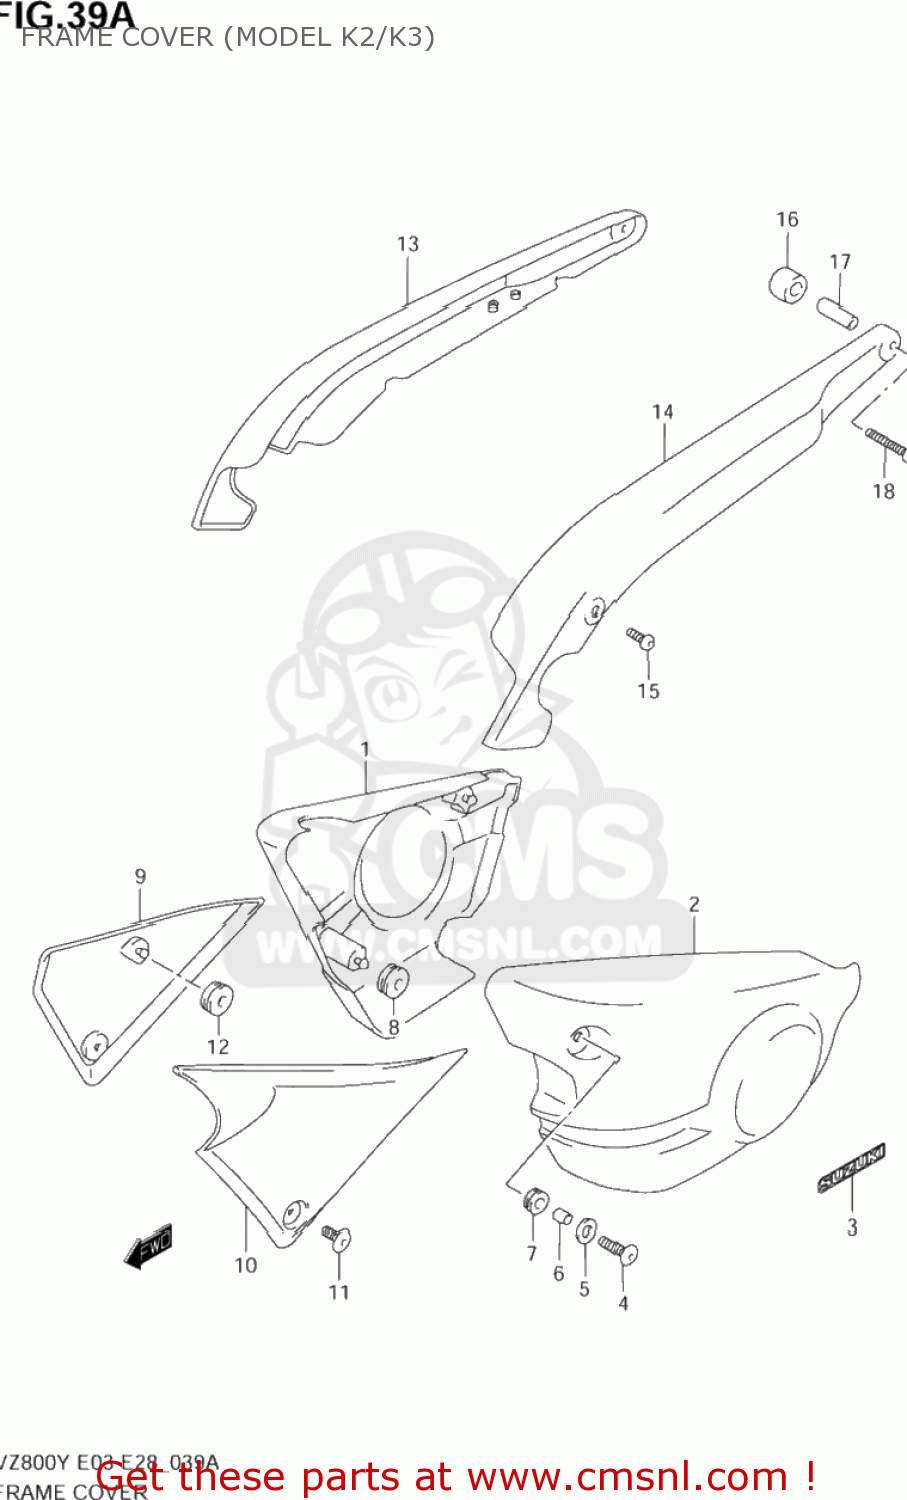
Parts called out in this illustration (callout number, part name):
1	COVER,FRAME,R
2	COVER,FRAME,L
3	EMBLEM,FRAME COVER CTR
4	SCREW(6X16)
5	WASHER(6.5X18X1)
6	SPACER(6.5X9X9)
7	CUSHION
8	CUSHION
9	COVER,FRAME HEAD,R
10	COVER,FRAME HEAD,L
11	SCREW(6X16)
12	CUSHION
13	COVER,FRAME RR,R
14	COVER,FRAME RR,L
15	BOLT(8X16)
16	CUSHION,FRAME RR COVER RR
17	SPACER(8.5X12X23.5)
18	BOLT
